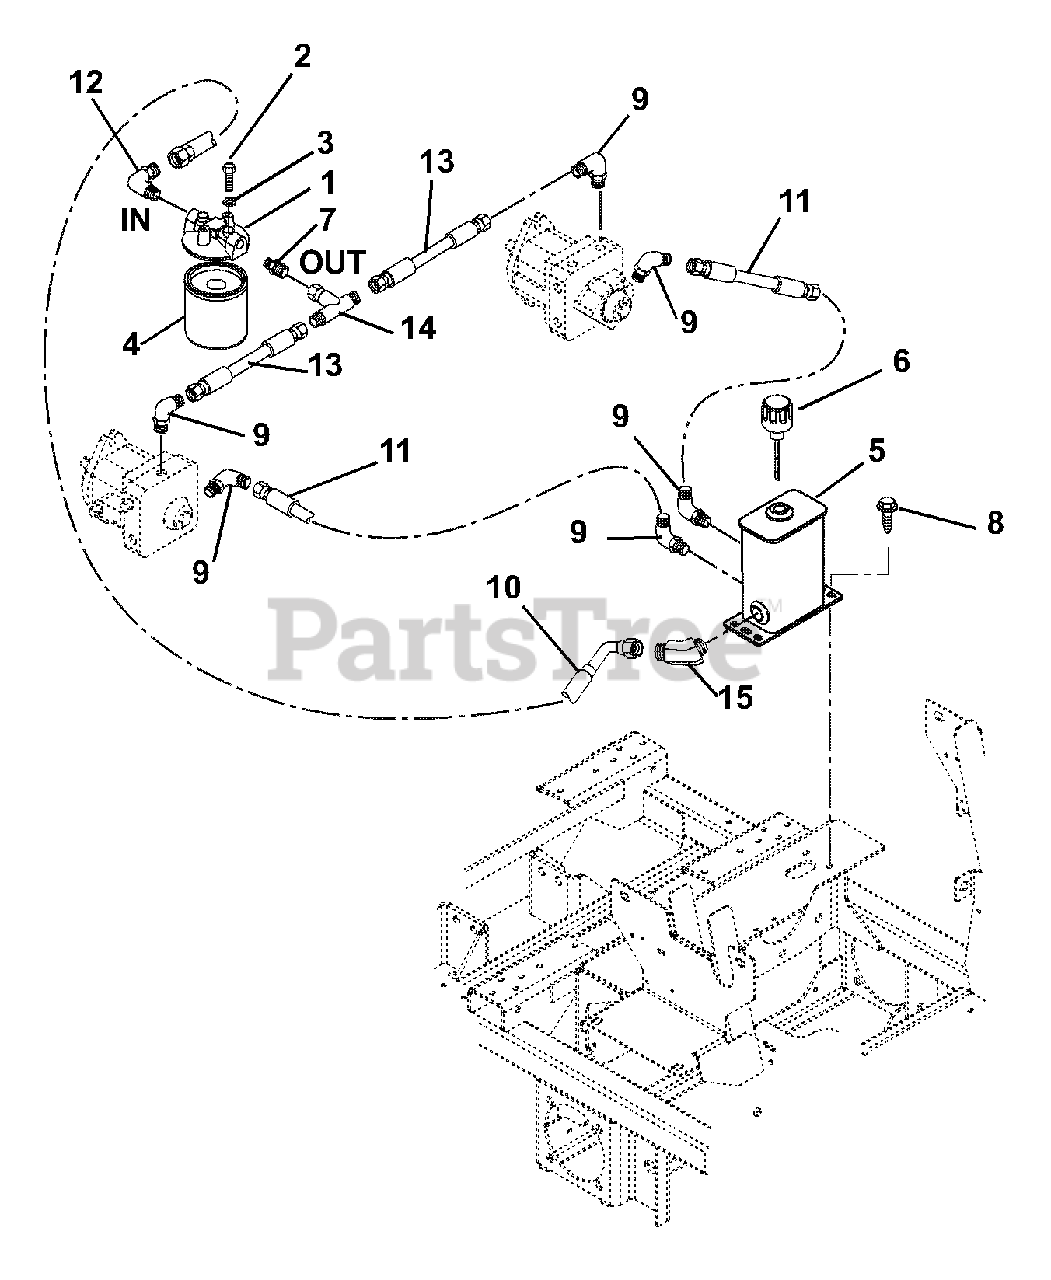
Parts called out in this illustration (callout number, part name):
1	FILTER HOUSING ZINGA ZAF11250
2	@BLT-HEX .25-20X.50 GR5 YWZC
3	@WSHR-LK .25X.062 REG YWZC
4	FILTER ELEMENT, ZINGA AE-25
5	WMT, HYDRAULIC TANK
6	BREATHER, DIPSTICK
7	FTG.HYD STR.M8O-M12O (F5OLO-S)
8	@SCR-TAP .38-16X.75 HWH TR YWZ
9	FTG. HYD. 90 EL M8F-M8O
10	HOSE, HYD. .50-19-0K F8F0-F8F9
11	HOSE,HYD..50-10-0K FO8J0-FO8JO
12	FTG. HYD 90 EL M8O-M12O
13	HOSE,HYD. .50-5-0K FO8J0-FO8J0
14	FTG.HYD TEE M8O-F8O-F8O
15	FTG,HYD 45DEG M8F-M80
